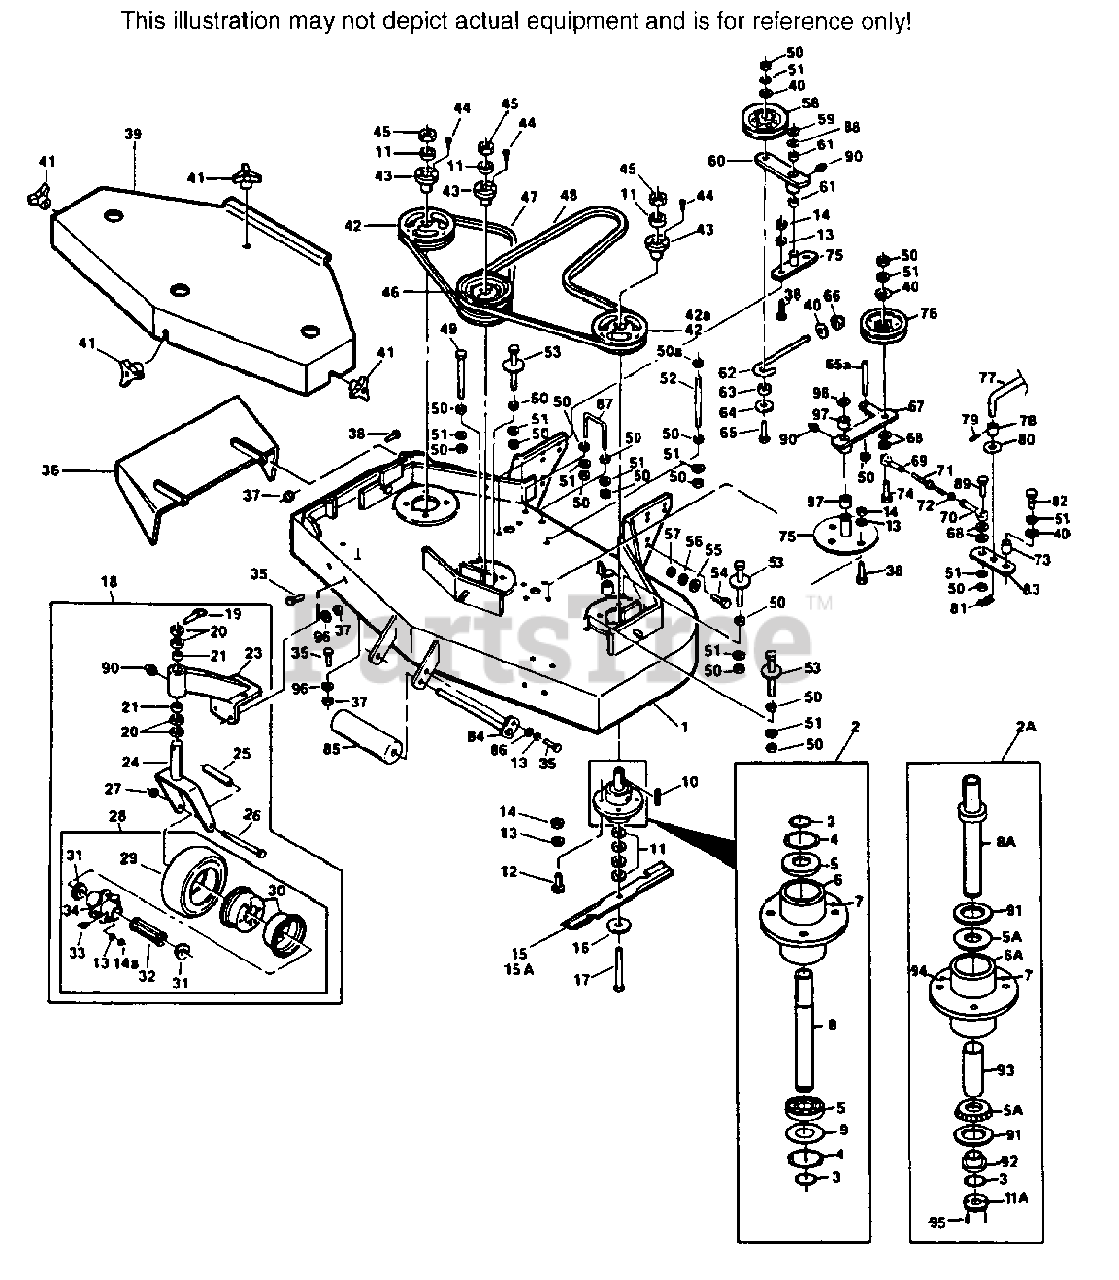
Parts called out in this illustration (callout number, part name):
2	CUTTER SPINDLE ASSY. BALL BEARING
2A	SPINDLE ASSEMBLY, TAPERED BEARING
3	RETAINING RING, 1" EXT.-INVERTED
4	RETAINING RING, 2-7/16" INT.BASIC
5	BEARING, CUTTER SPINDLE
5A	TAPERED BEARING
6	SPINDLE HOUSING
6A	SPINDLE HOUSING, TAPERED BEARING
7	GREASE FITTING STR. 5/16 SERR.
8	SPINDLE, CUTTER BLADE
8A	SPINDLE SHAFT, TAPPER BEARING
9	WASHER, 1-5/16 X 2-7/16 X 16 GA.
10	KEY, 1/4 X 1/4 X 2
11	SPACER, CUTTER BLADE
11A	SPACER, CUTTER BLADE, TAPERED
16	FLAT WASHER, 5/8" W
17	HEX HD. BOLT, 5/8-11 X 9-1/2"
18	CASTER ASSY, COMP.(INCL. 19-28)
19	QUICK PIN
20	SPACER, CASTER YOKE, 1/2" THICK
21	BRONZE BEARING
23	SUPPORT ASSY.(INCL. 21-90)
24	CASTER YOKE
25	SLEEVE, CASTER WHEEL BEARING
26	HEX HD BOLT, 1/2-13 X 5-1/2"
28	WHEEL ASSY.(INCL. 13-14, 29-34)
29	TIRE ONLY, CASTER WHEEL
29	INNER TUBE ONLY, CASTER WHEEL
30	RIM PAIR, CASTER WHEEL
31	RETAINER, BEARING, CASTER WHEEL
32	ROLLER BEARING, CASTER WHEEL
33	GREASE FITTING 45 DEG., 1/4-28
34	HUB ASSY.(INCL. BOLTS)
36	DISCHARGE CHUTE
37	HEX NUT, 5/16-18 ELASTIC STOP
40	WASHER 25/64 X 15/16 X 12 GA.
41	WING NUT, 3/8-16
42	PULLEY(INCLUDES 43-44)
43	TAPERED HUB
46	PULLEY, DOUBLE(INCLUDES 43-44)
50A	HEX NUT, 3/8-16, CENTERLOCK
52	SUPPORT, BELT COVER
53	BELT GUIDE
55	WASHER, 15/32 X 59/64 X 16 GA.
58	IDLER PULLEY, "V" GROOVE
59	RETAINING RING, 3/4" EXT. "E"
60	IDLER ARM ASSY.(INCLUDES 82 & 61)
61	BRONZE BEARING
62	J ROD, IDLER PULL
63	SPACER, J PULL ROD
64	WASHER, 3/8 X 1-1/2 X 16 GA.
66	HEX NUT, 3/8-16 ELASTIC STOP
67	IDLER ARM(INCLUDES ITEMS 97,90)
68	3/8" FLAT WASHER
69	ROD END L.H. THD.(SILVER)
70	ROD END R. H. THD.(GOLD)
71	LINK, TURNBUCKLE
72	3/8" 24 HEX NUT
73	SLEEVE, CAM CLUTCH
75	IDLER PIVOT
76	IDLER PULLEY, BELT CLUTCH
77	BLADE CLUTCH ROD, LOWER
78	SLEEVE, CLUTCH ROD
80	WASHER, 33/64 X 1 X 16 GA.
81	HAIR PIN LARGE
83	CAM LINK
87	BELT GUIDE
89	3/8-16 X 1 1/2" HEX HEAD BOLT
90	GREASE FITTING
91	SEAL
92	SPINDLE BUSHING
93	SLEEVE, CUTTER SPINDLE
94	RELIEF FITTING, CUTTER SPINDLE
97	BRONZE BEARING
98	RETAINING RING 1 1/8 EXT. "E"
